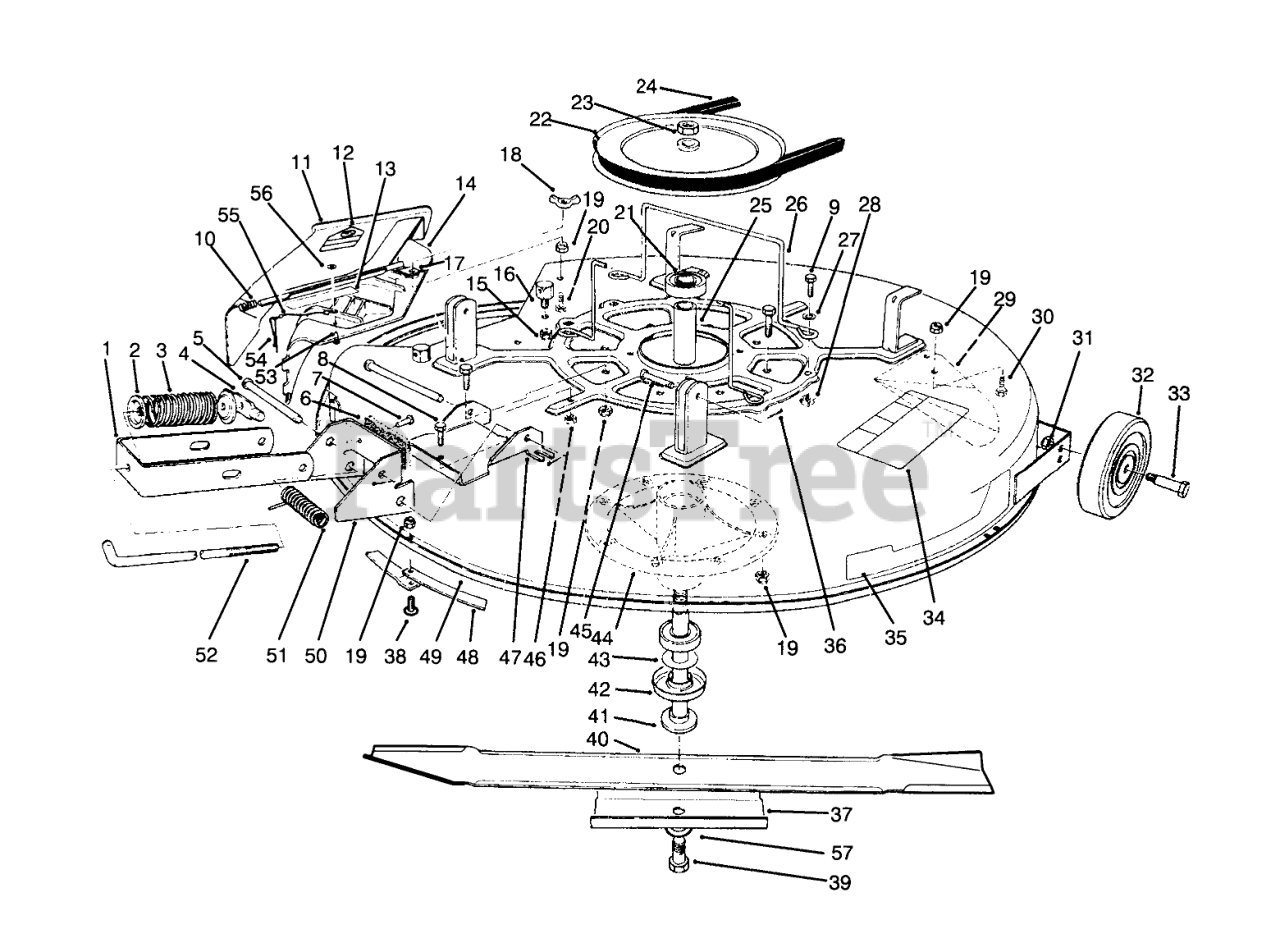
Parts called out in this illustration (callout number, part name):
1	Bracket-Engagement
2	RETAINER-SPR. TOP
3	SPRING-COMPRESSION
4	SHAFT-DECK ADJ.
5	PIN-CLEVIS
6	PAD-BRAKE
7	RIVET-BLIND
8	SCREW-HH
9	SCREW-HH
10	SPRING
11	Assembly-Deflector (Incl. Ref. #12)
12	DECAL-DANGER
13	DECAL-DANGER, DEFLECTOR
14	Assy.-Cover, Discharge (Incl. Ref. #53-56)
15	NUT-LOCK, NI
16	POST-PIVOT
17	Brace-Cover, Rear
18	NUT-WING
19	NUT-LOCK, NI
20	SCREW-HH
21	BEARING-BALL
22	PULLEY
23	NUT-HEX
24	V-BELT, DECK
25	SPACER-BEARING
26	GUIDE-BELT
27	WASHER-PLAIN
28	NUT-RETAINER
29	Kicker
30	SCREW-HH
31	NUT-LOCK, NI
32	WHEEL-DECK
33	BOLT-WHEEL
34	DECAL-DANGER, THROWN OBJECT
35	DECAL - RECYCLER 32"
36	PIN-COTTER
37	STIFFENER
38	SCREW-PPH
39	SCREW-HH
40	BLADE-RECYCLER
41	SHAFT-SPINDLE
42	SHIELD-BEARING
43	SPACER-HARDNED
44	SPINDLE
45	PIN-CLEVIS
46	NUT-HEX
47	Plate-Deck, Brake Mtg.
48	RING-DECK
49	Deck-Cutting
50	Assembly-Brake (Incl. Ref. #6-7)
51	SPRING
52	ROD-ENGAGEMENT
53	RIVET-BLIND
54	PIN-LOCKING, CHUTE
55	LANYARD
56	WASHER-PLAIN
57	WASHER-BELLEVILLE
